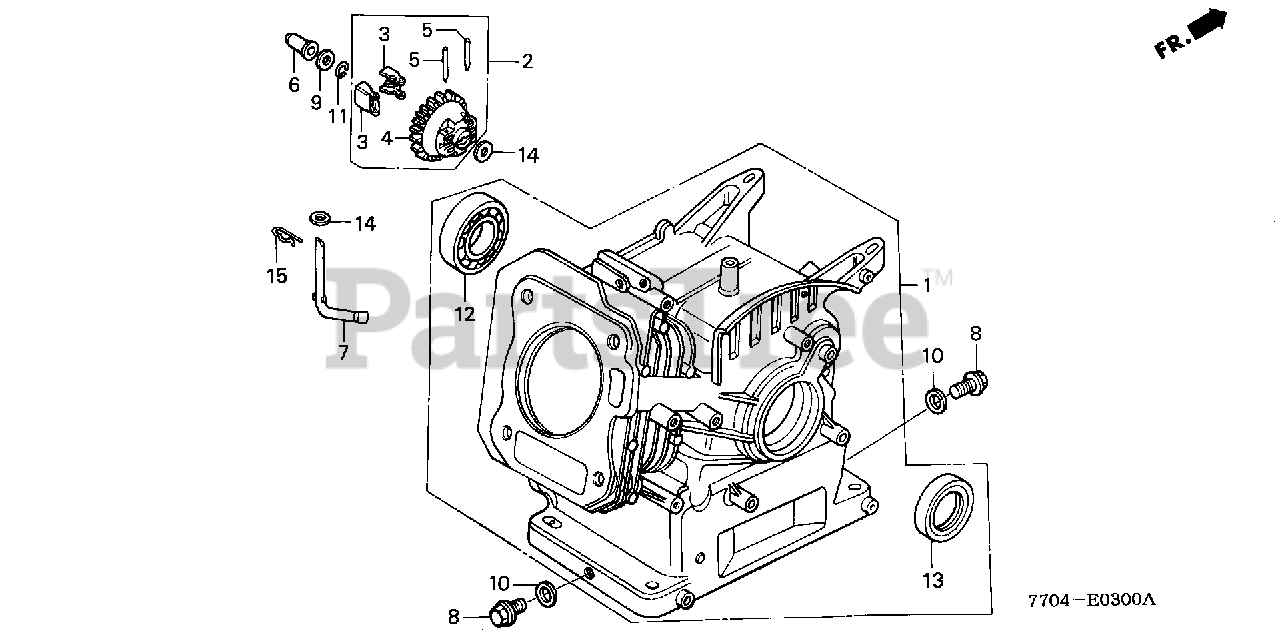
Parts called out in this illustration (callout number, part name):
1	CYLINDER ASSY.
2	GOVERNOR ASSY.
3	WEIGHT, GOVERNOR
4	HOLDER, GOVERNOR WEIGHT
5	PIN, GOVERNOR WEIGHT
6	SLIDER, GOVERNOR
7	SHAFT, GOVERNOR ARM
8	BOLT, DRAIN PLUG
9	WASHER, THRUST (6MM)
10	WASHER, DRAIN PLUG (10.2MM)
11	CLIP, GOVERNOR HOLDER
12	BEARING, RADIAL BALL (6205TMB) (NTN)
13	OIL SEAL (25X41X6)
14	WASHER, PLAIN (6MM)
15	PIN, LOCK (8MM)
